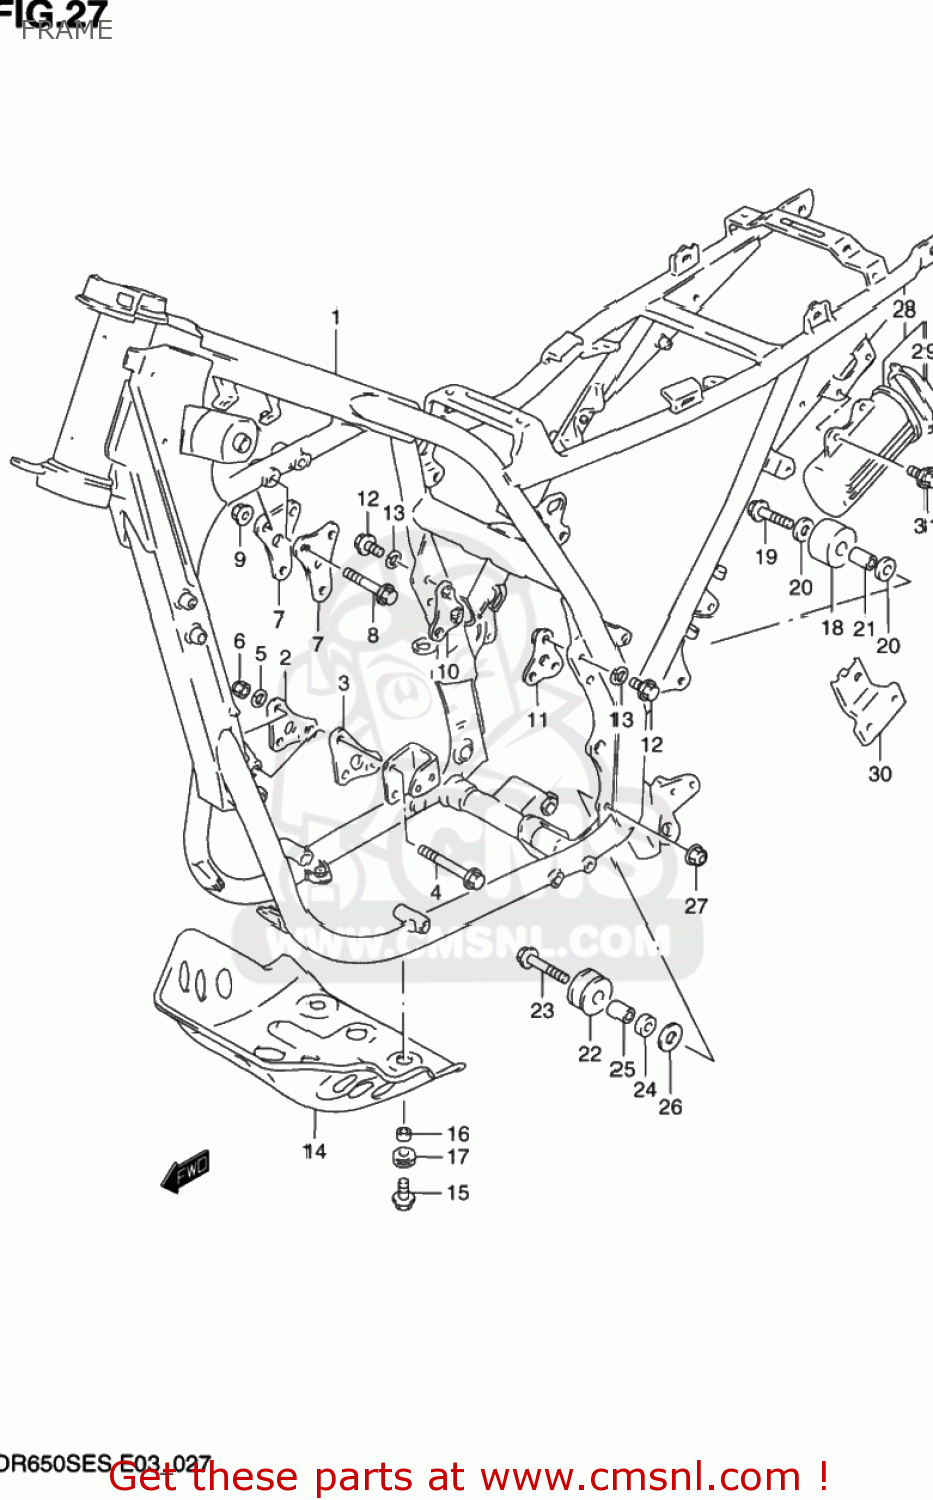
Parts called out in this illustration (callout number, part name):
1	FRAME
2	PLATE,ENG MTG FR,R
3	PLATE,ENG MTG FR,L
4	BOLT(8X72)
5	LOCK WASHER
6	NUT
7	PLATE,ENGINE MOUNTING
8	BOLT(8X50)
9	NUT
10	PLATE,ENG MTG RR,R
11	PLATE,ENG MTG RR,L
12	BOLT(8X20)
13	LOCK WASHER
14	PROTECTOR,ENGINE
15	BOLT 6X20
16	SPACER (7X9X7)
17	CUSHION
18	ROLLER,CHAIN CONTROL
19	BOLT(8X41)
20	WASHER (8.2X24X1.6)
21	SPACER (8.6X13.8X28)
22	ROLLER,CHAIN CONTROL
23	BOLT 8X50
24	SPACER,LOWER
25	SPACER(8.6X12X25.5)
26	WASHER
27	NUT
28	HOLDER,TOOL
29	CAP,HOLDER
30	BRACKET,TOOL HOLDER
31	BOLT(6X16)
